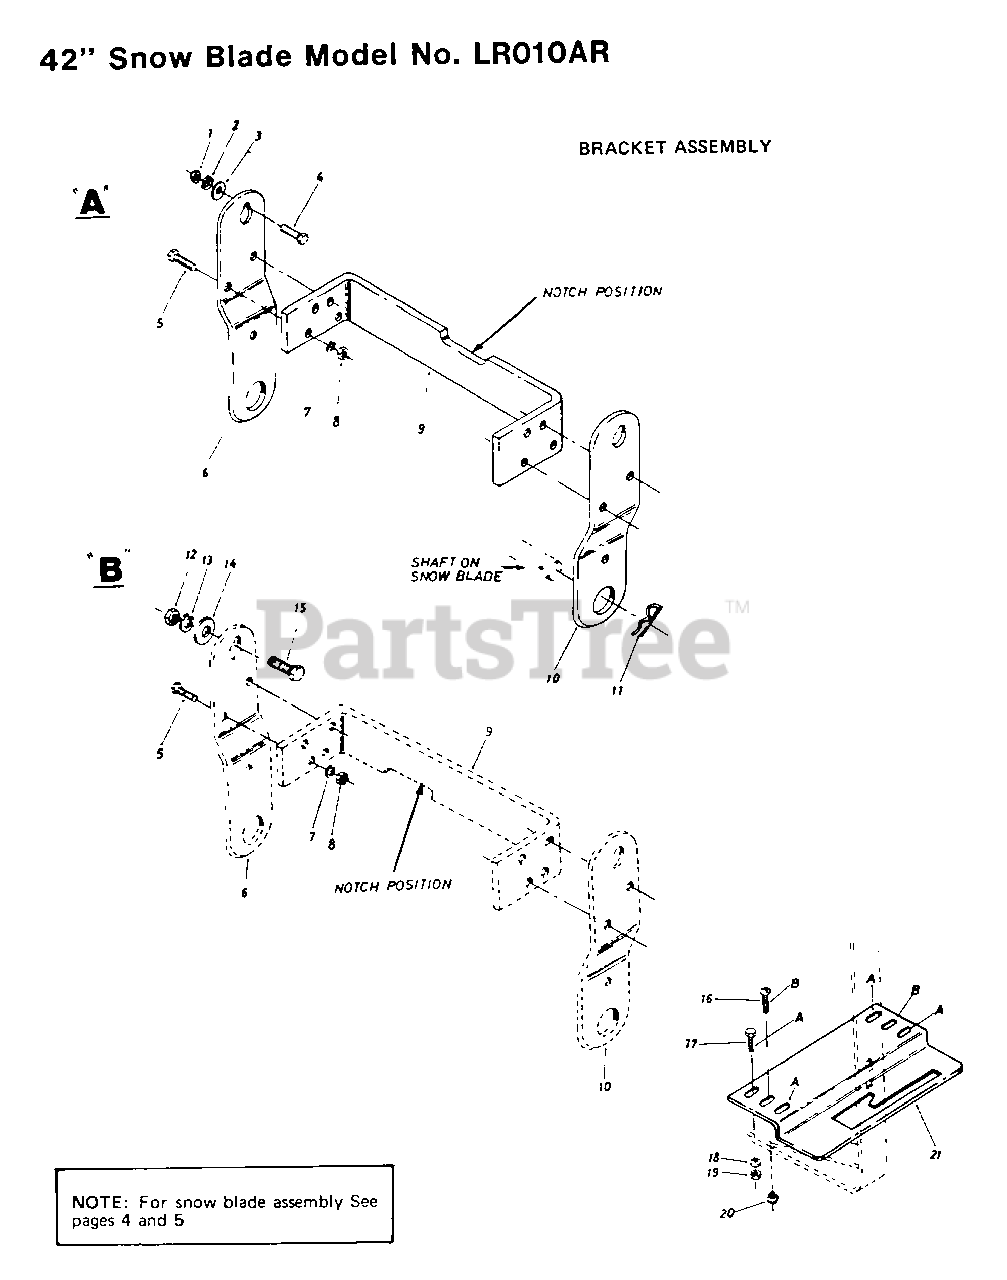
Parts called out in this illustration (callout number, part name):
6	MOUNTING BRKT
9	CROSS TIE BRKT
10	MOUNTING BRKT
11	HAIR PIN COTTER
21	LIFT LOCK PLATE
